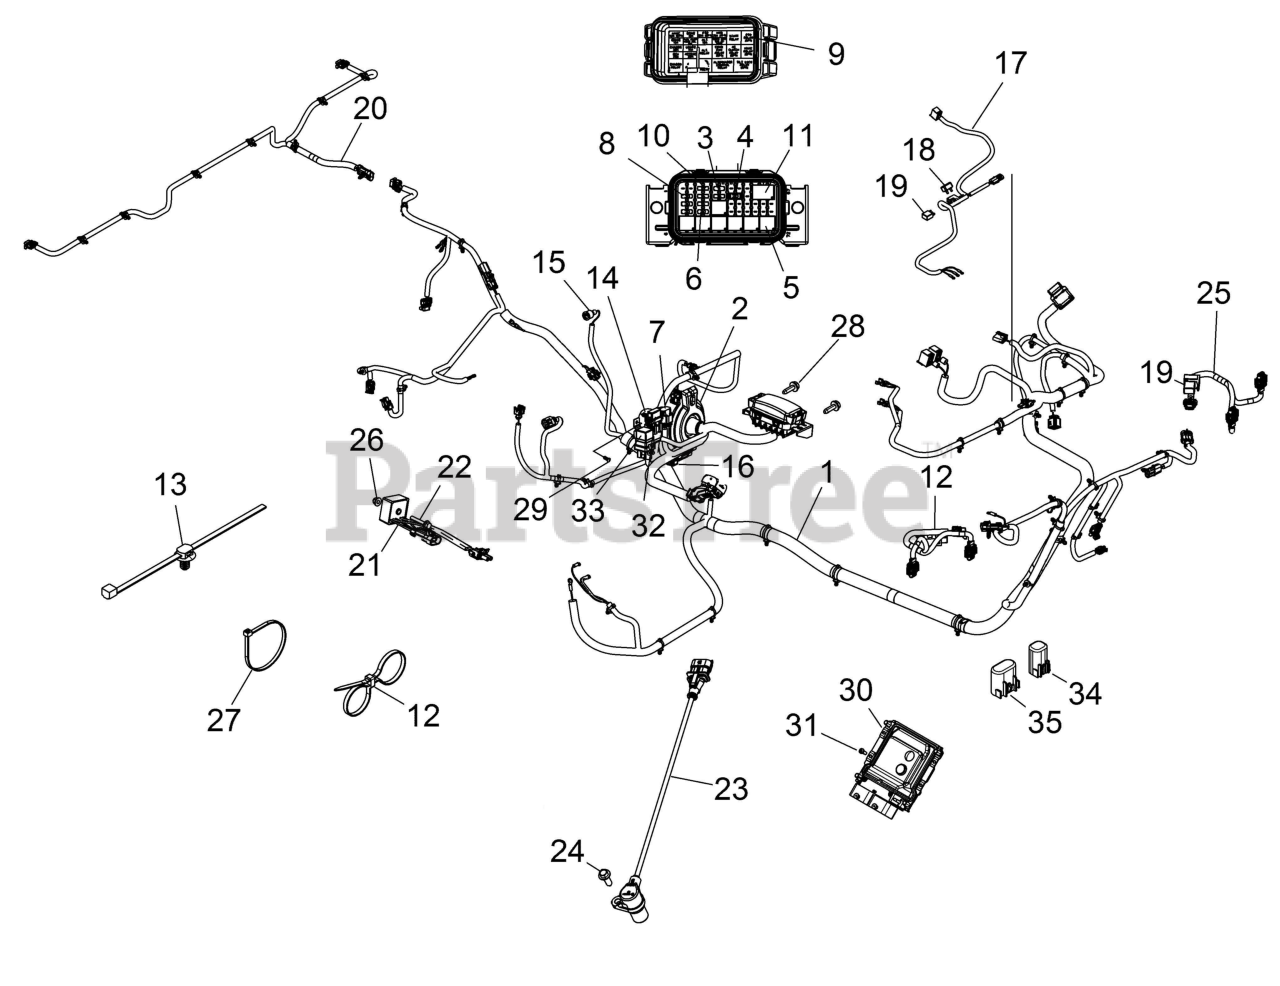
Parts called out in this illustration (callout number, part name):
1	HARNESS-CHASSIS,DSL,EPS
1	KIT, FUSIBLE LINK, 2MM
1	KIT, FUSIBLE LINK, 1MM
1	KIT, FUSIBLE LINK, .8MM
2	GROMMET-CHASSIS HARNESS
3	FUSE-5A,MINI BLADE
4	BREAKER-CIRCUIT,20 AMP
5	RELAY-SPST,SERIES 303,SEALED
6	FUSE,PARK,20 AMP,(10)
7	COVER-DIAGNOSTIC,W/CLIP
8	FUSE,MAIN,30 AMP,(10)
9	DECAL, FUSE BLOCK
10	FUSE, MINI BLADE, 15 AMP
11	RELAY-SPDT,SERIES 301,SEALED
12	CABLE TIE
13	CLIP-ROUTING
14	CLIP, X-MAS-TREE
15	BOOT, OIL PRESSURE SWITCH
16	TVS, 30VOLT
17	HARNESS-BOX,LIFT
18	BREAKER-CIRCUIT,20 AMP,SEALED
19	RELAY-MICRO,SPST,35A,SEALED
20	HARNESS-BOX-ARIENS SPLY
21	RELAY, SOLID STATE,9A,LONG LD
22	BOLT-M6X1.0X35,HXFLG/SH-OLV D
23	SENSOR-CRANK POSITION
25	HARNESS-HEADLIGHT,ARIENS
26	NUT-M6X1.0,FLG-NYLOC-OLIVE D
27	CABLE TIE (10)
28	SCR-M6X1.0X20,HXHD,FLG,TDFM,BL
29	CLIP, PLASTIC DART, NYLON
30	SERVICE ECU, ALL MY11 800 DOM
31	SCR-#10X1/2-HI/LO-PN-T25,TRX-M
32	FUSE-80 AMP
33	RELAY-GLOW PLUG
34	CONNECTOR-CAP,EPS SIGNAL
35	CONNECTOR-CAP,EPS POWER
